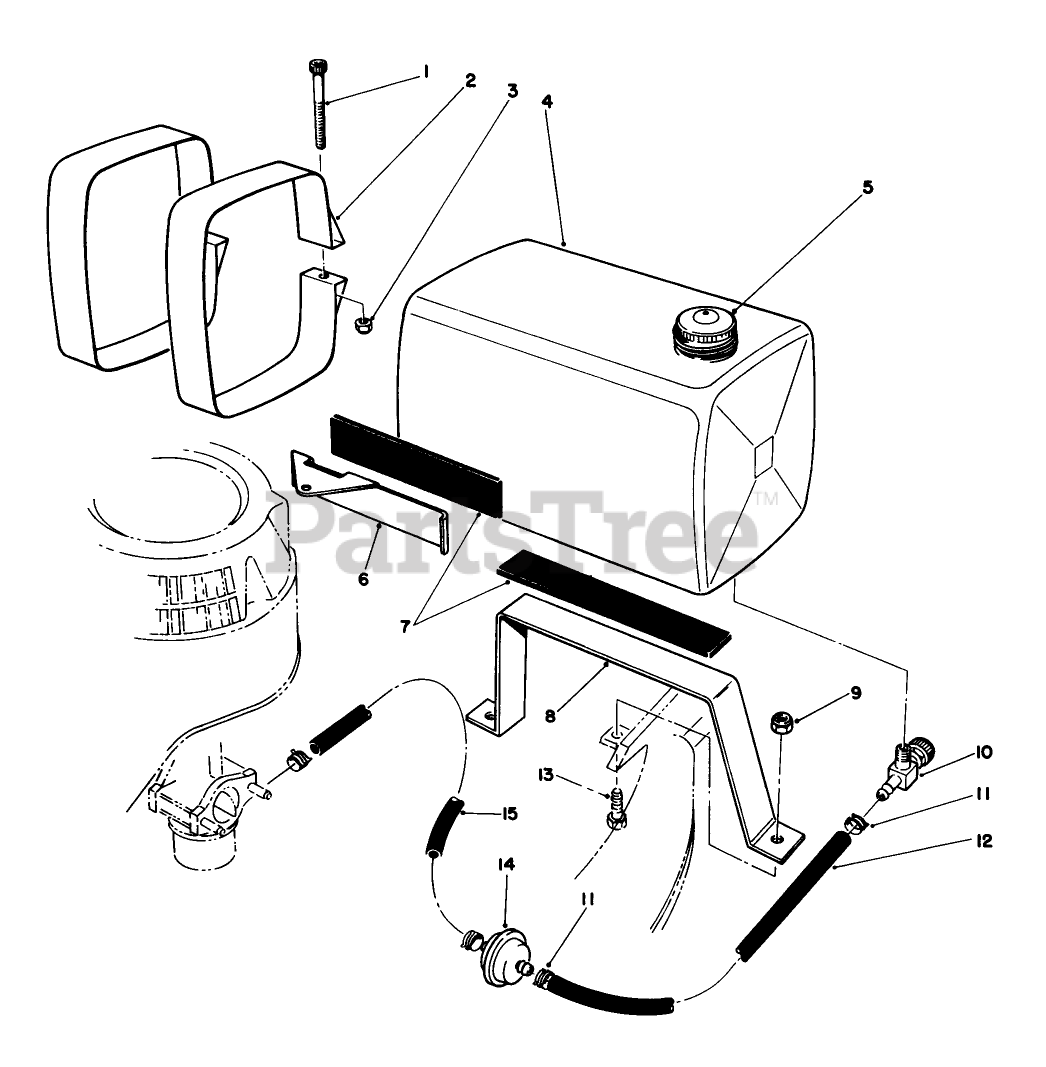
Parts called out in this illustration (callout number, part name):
1	SCREW-HSH
2	TANK STRAP WA
3	NUT-HEX
4	5 QT GAS TANK
6	FRT TANK MOUNT *
7	ISOLATOR PAD
8	TANK BOTTOM MOUNT *
9	NUT-LOCK, NI
11	CLAMP-FUEL LINE
12	HOSE-FUEL
13	SCREW-HH
14	FILTER-FUEL
15	HOSE-FUEL
